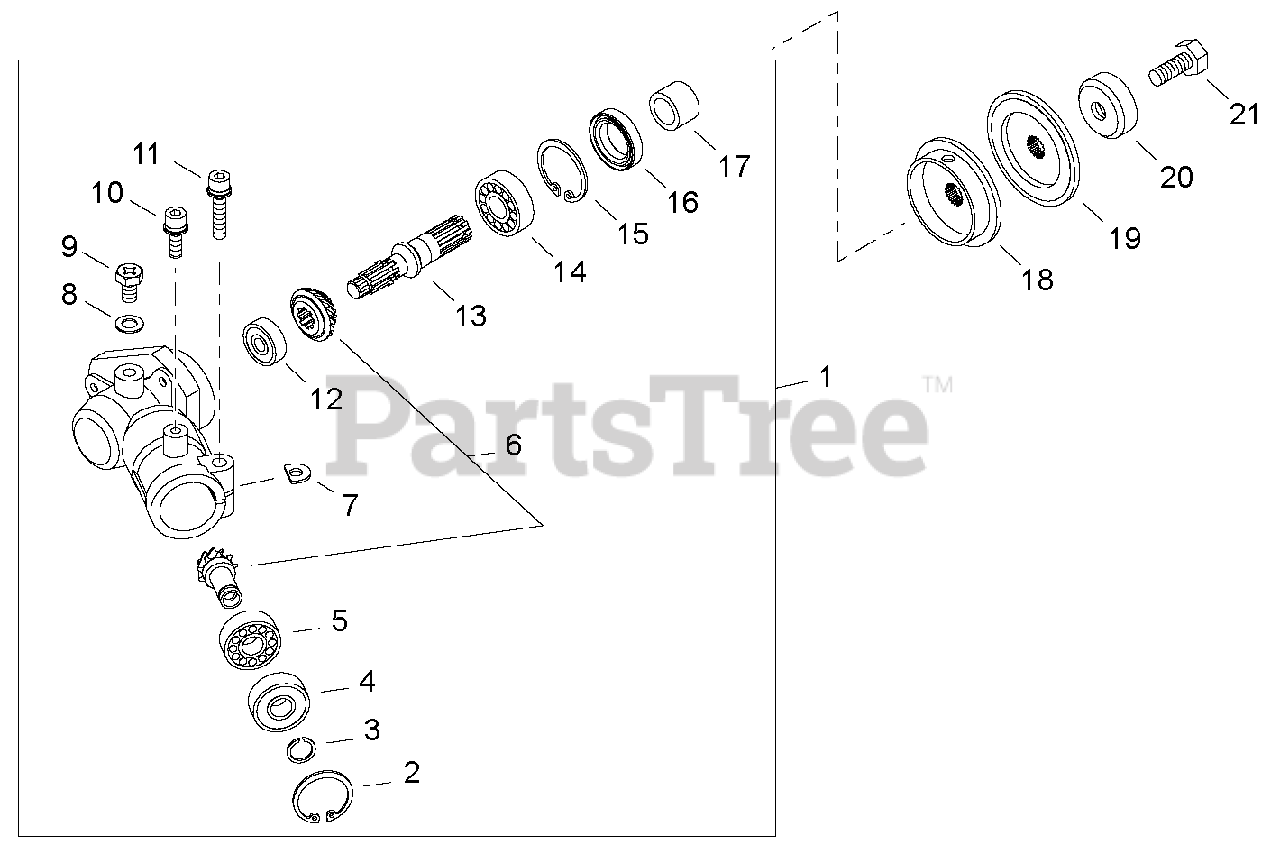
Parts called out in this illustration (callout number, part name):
1	GEAR CASE ASSY
2	RING, SNAP Ø24
3	RING, SNAP
4	BEARING, BALL 609ZZ
5	BEARING, BALL 609
6	GEAR SET
7	D-WASHER
8	WASHER 6.5×11.5×0.8
9	BOLT M6×10
10	BOLT M5×16
11	BOLT M5×25
12	BEARING, BALL 608 DDU
13	SHAFT, GEAR
14	BEARING, BALL 6001
15	RING, SNAP Ø28
16	SEAL, OIL
17	SPACER
18	PLATE, ADAPTOR - UPPER
19	PLATE, ADAPTOR - LOWER
20	GUARD, BOLT
21	BOLT 8
